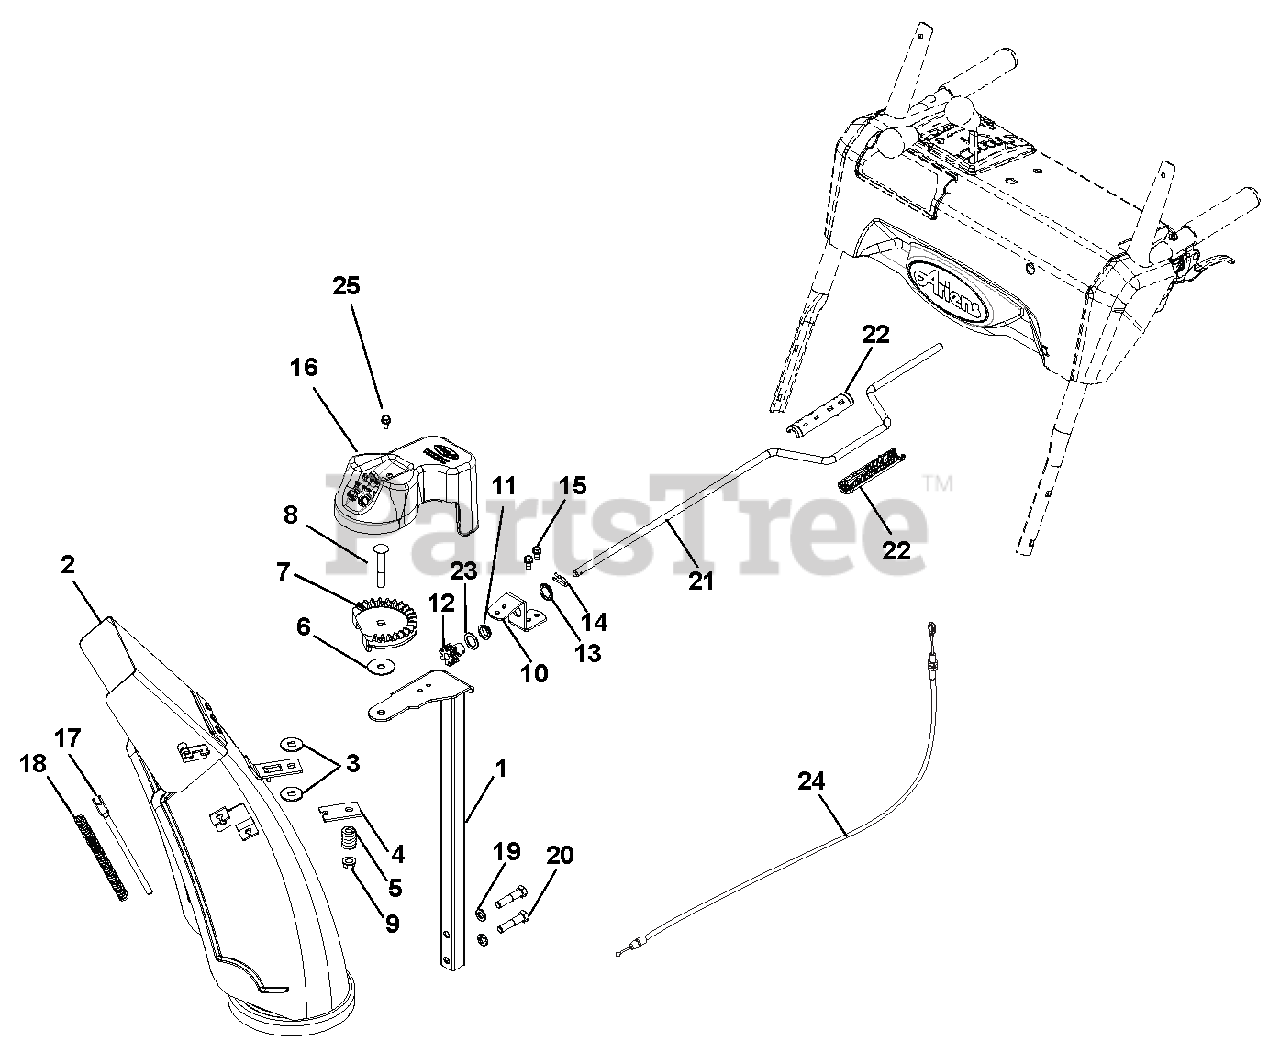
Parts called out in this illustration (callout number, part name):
1	PEDESTAL, CHUTE - CRANK
2	CHUTE, DISCHARGE W/CAP & DECAL
3	FRICTION WASHER
4	PLATE, FRICTION
5	SG-COMP .187X.56X1.62
6	@WSHR-FL-STL .406X1.25X.10 ZC
7	CHUTE GEAR
8	@BLT-RDHDSQNK .38-16X2.50 G5YZ
9	@NUT-LK-TOP-FLG .38-16 YWZC
10	BRACKET, PINION GEAR
11	BUSHING, POLYLINER-.63 SNAPIN
12	PINION GEAR W/BRACKET
13	PUSHNUT .625
14	PIN, SPRING CLIP
15	SCR-TAP .25-20X.50 HWH TR YWZ
16	GEAR COVER ASSY LG SHEAR BOLT
17	ROD, DEFLECTOR CAP
18	SG-COMP .08X.40X6.50 14#/IN
19	@WSHR-LK .38X.094 REG YWZC
20	@BLT-HEX .38-16X1.75 GR5 YWZC
21	ROD, CHUTE CRANK
22	KNOB, CRANK-SNAP
23	WSHR-THRST .625 X 1.0 X .03
24	CABLE, DEFLECTOR-COATED
25	SCR-TAP .25-20X.50 LGHWH TR YZ
